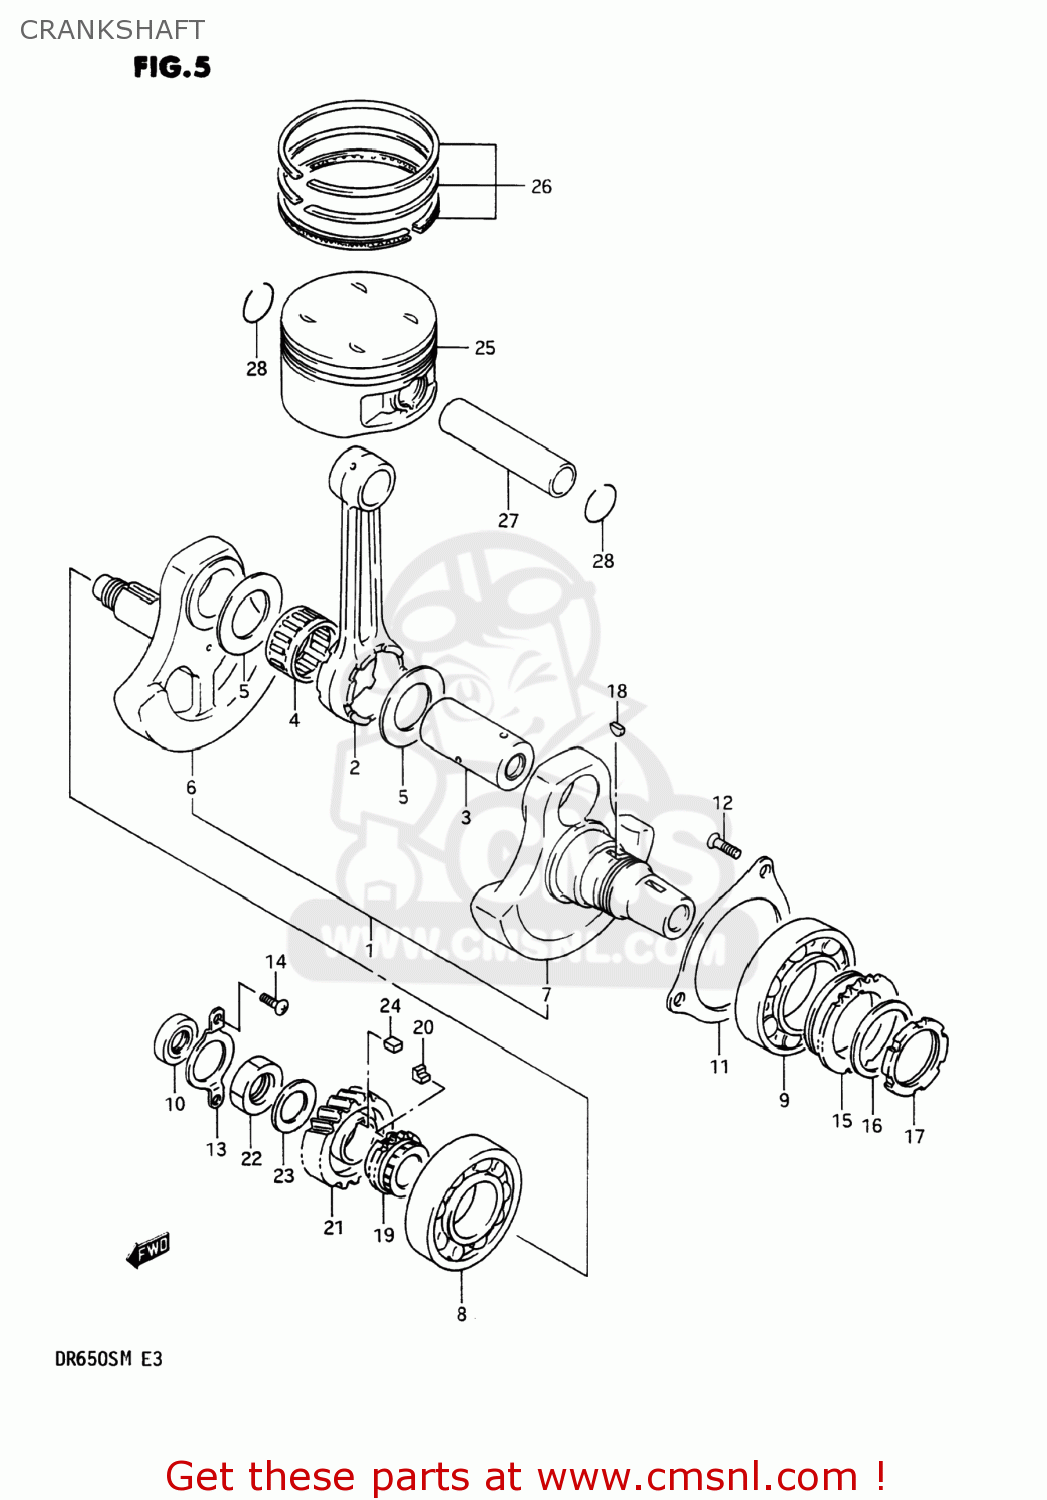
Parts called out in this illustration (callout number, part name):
1	CRANKSHAFT ASSY
2	ROD,CONNECTING
3	PIN,CRANK
4	BEARING
5	WASHER(35X55X1)
6	CRANKSHAFT,RIGHT
7	CRANKSHAFT,LEFT
8	BEARING(35X80X21)
9	BEARING
10	SEAL,OIL(16X30X6)
11	RETAINER,CRANKSHAFT BEARING,L
12	SCREW
13	RETAINER,CRANKSHAFT BEARING,R
14	SCREW
15	SPROCKET,BALANCER DRIVE
16	WASHER
17	NUT,FLYWHEEL
18	KEY
19	SPROCKET,CAM CHAIN DRIVE
20	KEY,SPROCKET
21	GEAR,PRIMARY DRIVE
22	NUT (20MM)
23	WASHER
24	KEY
25	PISTON
26	RING SET,PISTON
27	PIN,PISTON
28	CIRCLIP
